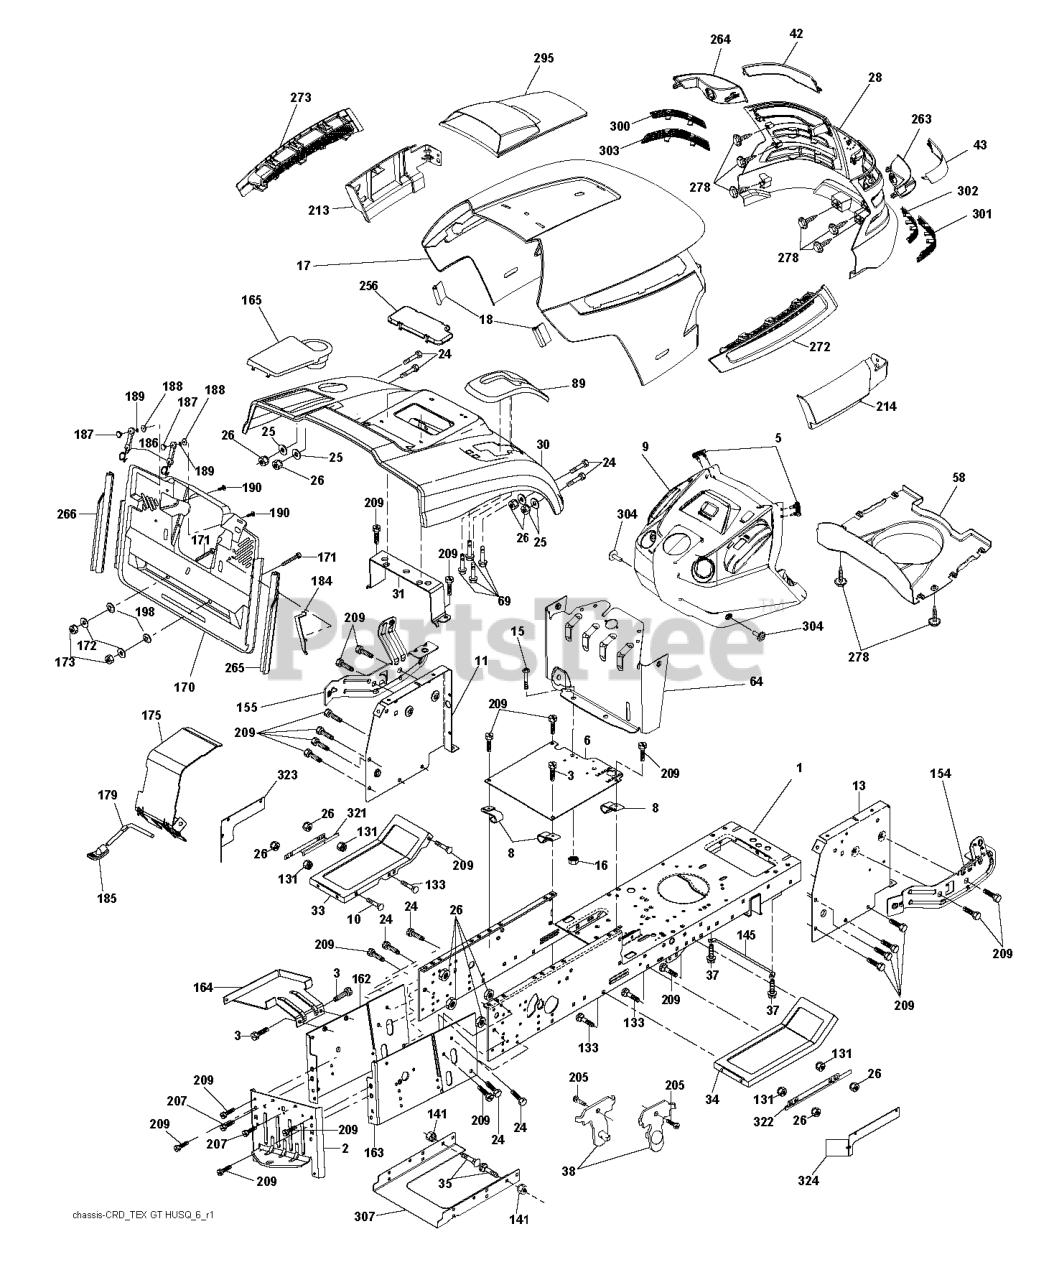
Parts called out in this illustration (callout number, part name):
2	DRAWBAR
3	SCREW 3/8-16X3/4
5	BUMPER DASH
6	PLATE
8	CLIP,INSULATOR
10	BOLT.3/8-14X1.25
11	PANEL DASH LH
13	PANEL DASH RH
15	Screw, Machine, Truss Head 5/16-18 UNC x 3/4
16	NUT
17	HOOD
18	BUMPER.HOOD.TEX.HUSQVARNA
25	WASHER
26	NUT
28	GRILL.ASM.HUSQ.TG/CRD.W/TRIM
30	CONSOLE.CRD.AUTO.GRY
31	BRACKET SUPPORT FENDER
33	FOOTREST PNT LH
34	FOOTREST PNT RH
37	Screw 5/16-18 x 1/2 Hex, Self Tapping 5/16-18 x 1/2
38	BRACKET ASM PIVOT MOWER REAR
42	LENS.LH.TEX.GT.HUSQ.CL
43	LENS.RH.TEX.GT.HUSQ.CL
58	AIR.DUCT.HOOD.TEX.GT.HUSQ
69	SCREW.HI-LO.CONSOLE
89	CONSOLE.CRD.AUTO.GREY.2005
131	NUT.HEX.3/8-16UNC
133	BOLT D
141	NUT LOCK FLG 3/8-16 UNC
145	ROD.PIVOT.HOOD
162	BRACKET
163	BRACKET EXTEN CHASSIS RH CRD
165	COVER.BATTERY.BGGR.ELE
172	WASHER
175	DOOR TRAP
179	ROD PIVOT FBI
184	BRACKET.ACTUATOR.BAGGER.SRD
186	LATCH ASSY
187	WELDNUT
189	LOCKWASHER #10
190	SCREW
207	SCREW, 5/16-18 X 1/2
209	SCREW, 3/8-16X3/4
213	SKIRT.HOOD.SIDE.HUSQ.LH.GREY
214	SKIRT.HOOD.SIDE.HUSQ.RH.GREY
256	COVER FENDER CRD
263	BEZEL.RH.TEX.GT.HUSQ
264	BEZEL.LH.TEX.GT.HUSQ
265	SEALING
266	SEALING
272	VENT.SIDE.HOOD.HUSQ.RH.GREY
273	VENT.SIDE.HOOD.HUSQ.LH.GRAY
278	SCREW.#10 X 0.750.BOS
295	HOOD VENT
300	INSERT.HEX.GRILL.HUSQ.
301	INSERT.HEX.GRILL.HUSQ.GREY
302	INSERT.HEX.GRILL.HUSQ.
303	INSERT.HEX.GRILL.HUSQ.
304	SCREW 14-20 X 5/8
321	SHIELD INNER LEFT
322	SHIELD INNER RIGHT
323	PLATE LEFT
324	PLATE RIGHT
